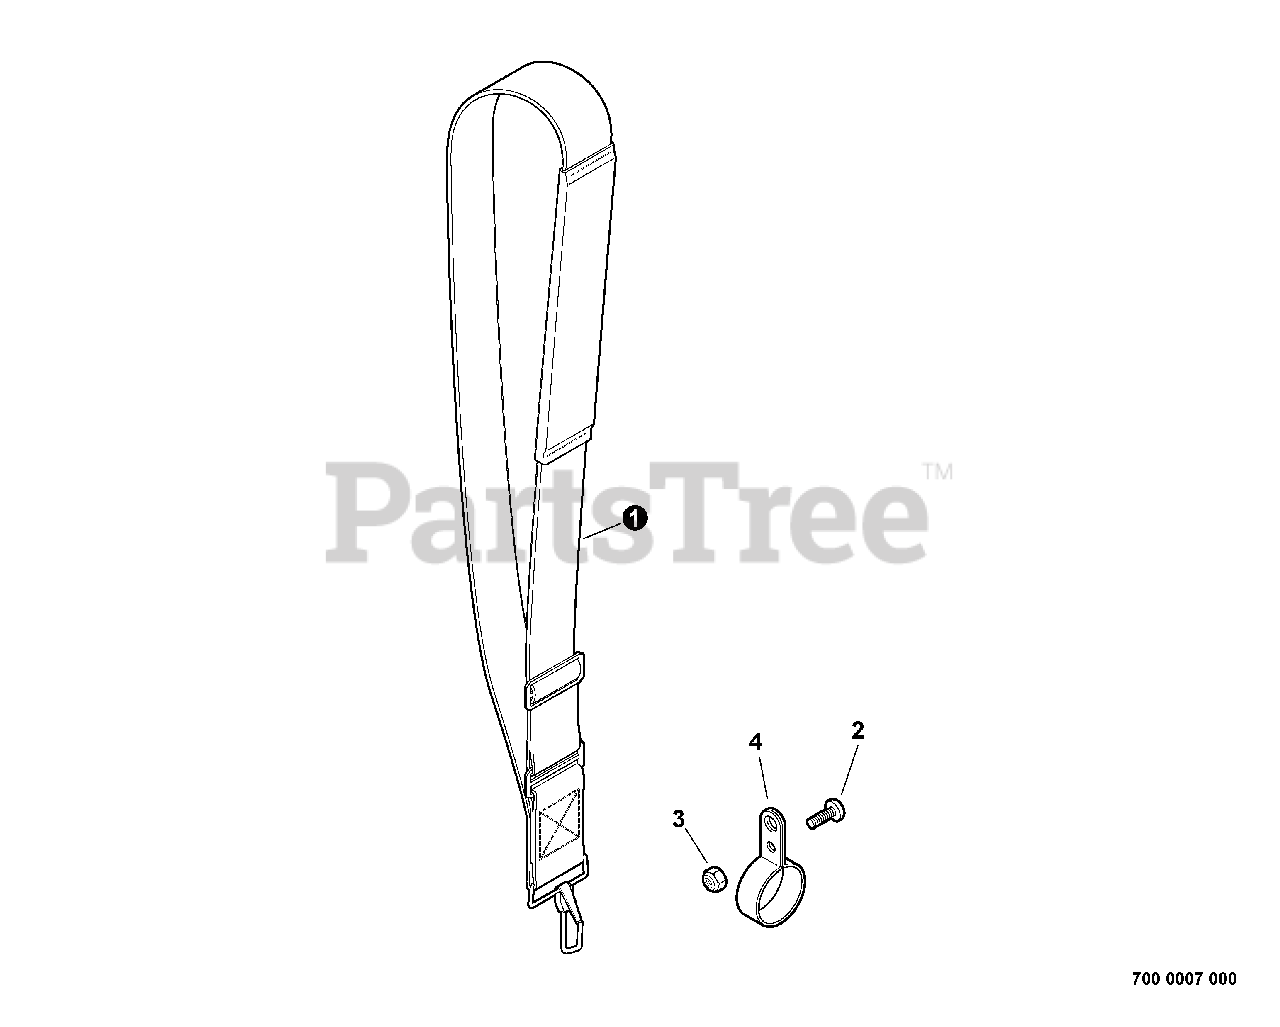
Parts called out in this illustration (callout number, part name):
1	SHOULDER STRAP ASSY
2	SCREW - 5X10
3	LOCKNUT - 5
